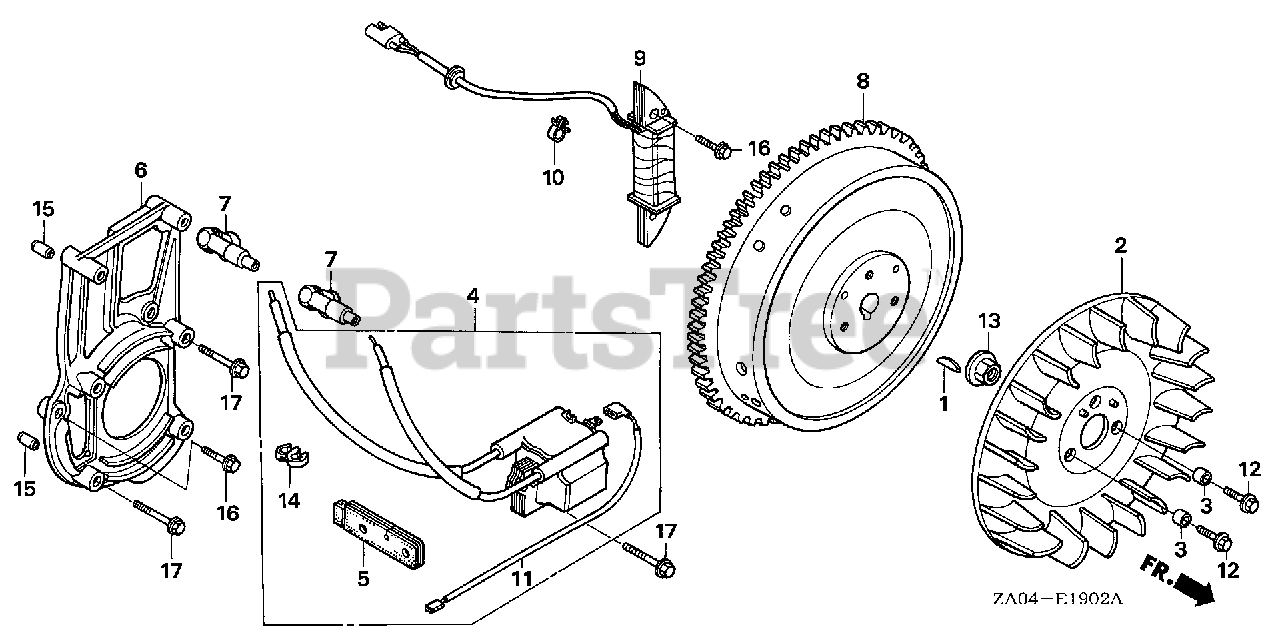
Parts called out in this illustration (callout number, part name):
1	KEY, SPECIAL WOODRUFF (25X18)
2	FAN, COOLING
3	COLLAR, FAN
4	COIL ASSY., IGNITION
5	GROMMET, IGNITION WIRE
6	STAY, IGNITION SYSTEM
7	CAP ASSY., NOISE SUPPRESSOR
8	FLYWHEEL
9	COIL ASSY., CHARGE
10	CLIP, IGNITION WIRE (8MM)
11	WIRE, ENGINE STOP
12	BOLT, FLANGE (6X16)
13	NUT, SPECIAL (16MM) (1)
14	CLIP, IGNITION WIRE
15	PIN A, DOWEL (8X10)
16	BOLT, FLANGE (6X22)
17	BOLT, FLANGE (6X28)
